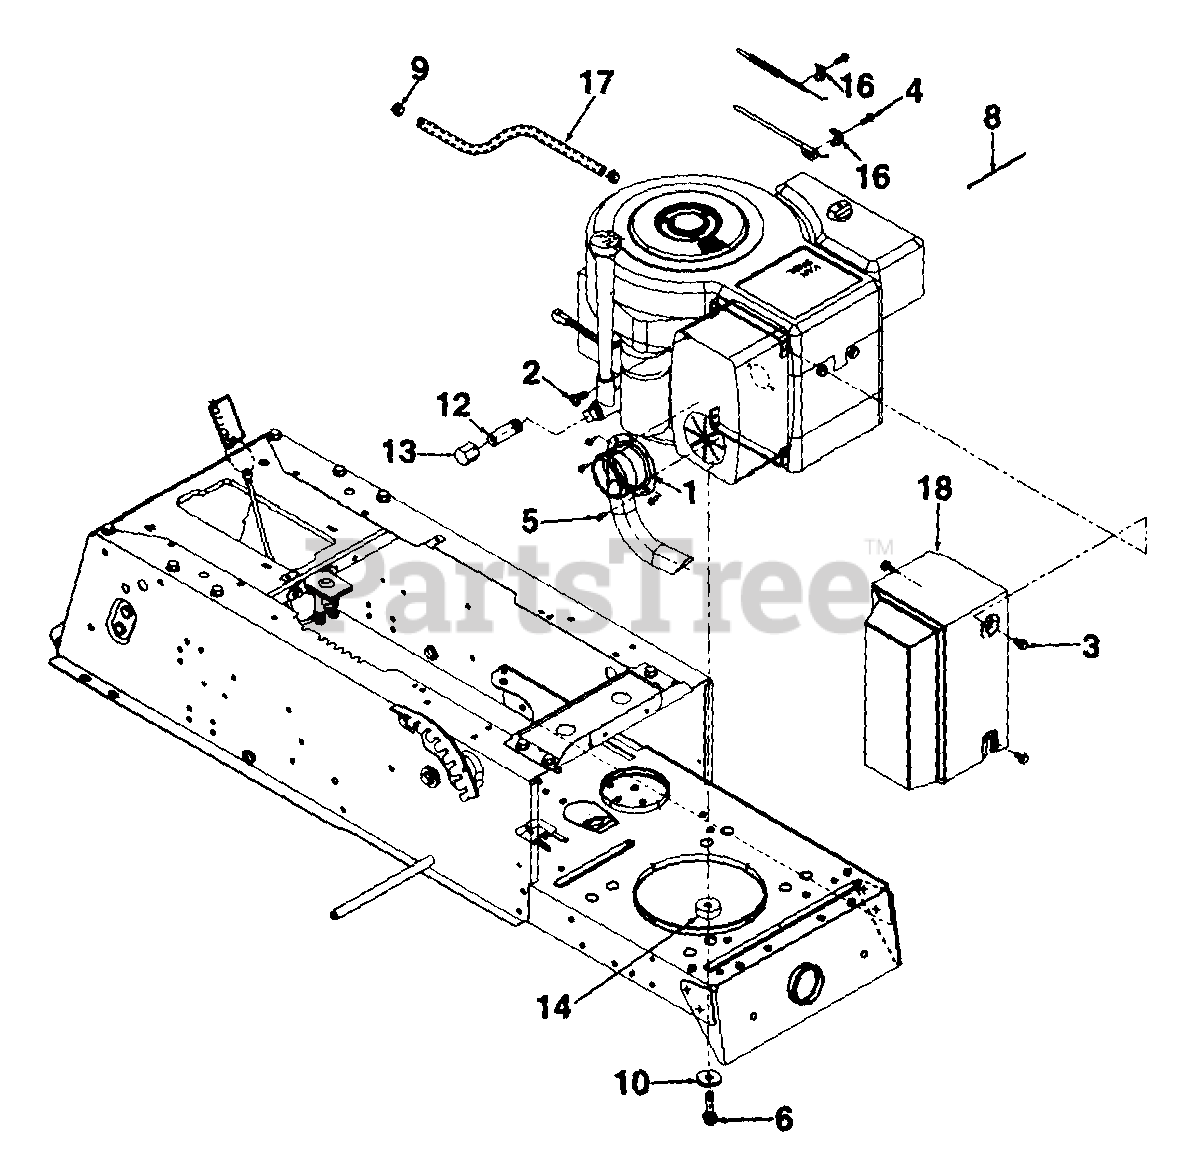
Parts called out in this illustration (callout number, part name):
1	Exhaust Pipe Ass'y.
2	Pan Mach. Scr. 5/16-18 x .75"
3	Hex Tap Scr. 1/4-20 x .5" Lg.
4	Hex Tap Scr. #10-32 x 5/8" Lg.
5	Hex Tap Scr. #8-32 x .38" Lg.
6	Hex TT-Tap Scr. 3/8-16 x 1.5"
10	Fl-Wash. 3/8" I.D. x 1.25" O.D.
12	Pipe Nipple 3/8-18 NPT.
13	Oil Drain Cap
14	Shld. Spacer .38" I.D. x 1.25"
16	Casing Clamp
17	Fuel Line
18	Muffler Heat Shield Ass'y.
